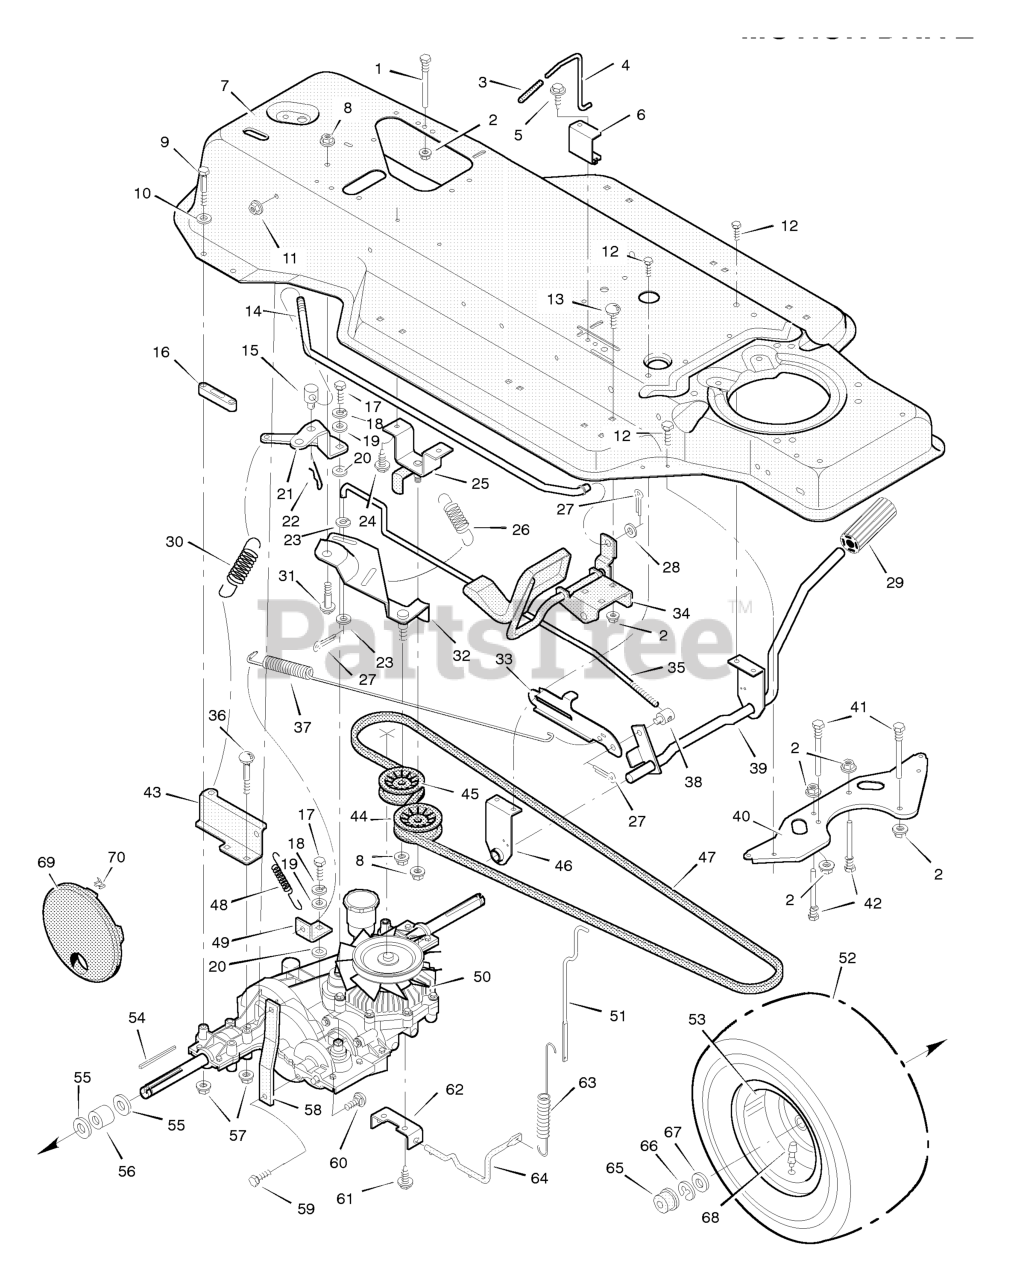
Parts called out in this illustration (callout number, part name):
1	Guide, Belt
2	Nut, Flange
4	Rod, Parking Brake
6	Bracket, Guide
7	Frame Assembly
8	Nut, Flange
10	Washer
11	Nut, Flange
13	Bolt, Carriage
14	Rod, Control
15	NUT, Adjusting, 1/2-13
16	Spacer, Hydro
18	Lockwasher
21	Lever, Control
22	Hair Pin
23	Washer
25	Idler Mount Assembly
26	Spring, Extension
27	Cotter Pin
29	Pedal
30	Spring, Extension
31	Shoulder Bolt
32	Idler Bracket Assembly
33	Latch, Parking Brake
34	Pedal Assembly
35	Clutch Rod
36	Carriage Bolt
37	Spring, Extension
38	Nut, Adjusting
39	Pedal Lever Assembly
40	Plate, Belt Guide
41	Screw, Guide
42	Screw, Guide
43	Bracket, Spring Mount
44	Idler Pulley
45	Idler Pulley
46	Support, Pedal
47	V- Belt
48	Spring, Extension
49	Lever, Brake
50	Transaxle **
51	Rod, Dump Valve
52	Wheel & Tire Assembly
53	Tire *
54	Square Key
56	Spacer, Wheel
57	Nut, Flange
58	Strap, Torque
60	Carriage Bolt
62	Bracket, Dump Valve
63	Spring, Extension
64	Rod, Dump Valve
65	Hub Cap
66	E- Ring
68	Valve Stem
69	Disc, Wheel
70	Clip, Retainer
